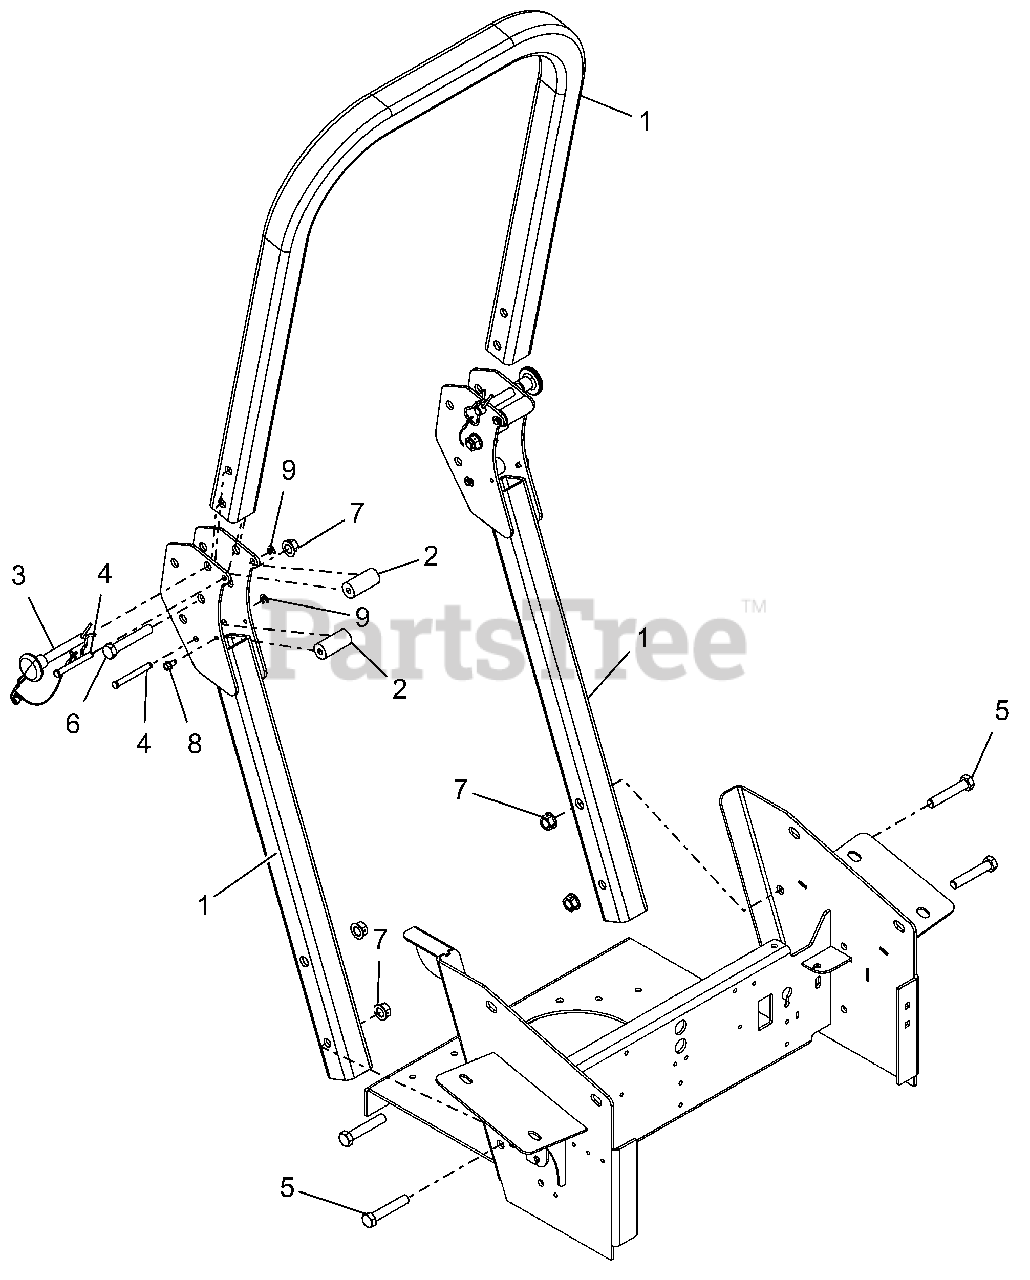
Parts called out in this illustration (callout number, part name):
1	ROPS, PT/PT100 REPLACEMENT
2	BUMPER, ROPS ANTI-VIBRATION
3	PIN, ROPS W/LANYARD
4	PIN, 5/16 X 2-9/16 WITH GROOVE
5	@BLT-HEX .50-13X2.75 GR5 YWZC
6	@BLT-HEX .50-13X3.00 GR5 YWZC
7	NUT-LK-CTR-FLG .50-13 YWZC
8	SCR-TAP .25-20X.50 HWH TR YWZ
9	RING, RETAINING-E .312 X .025
